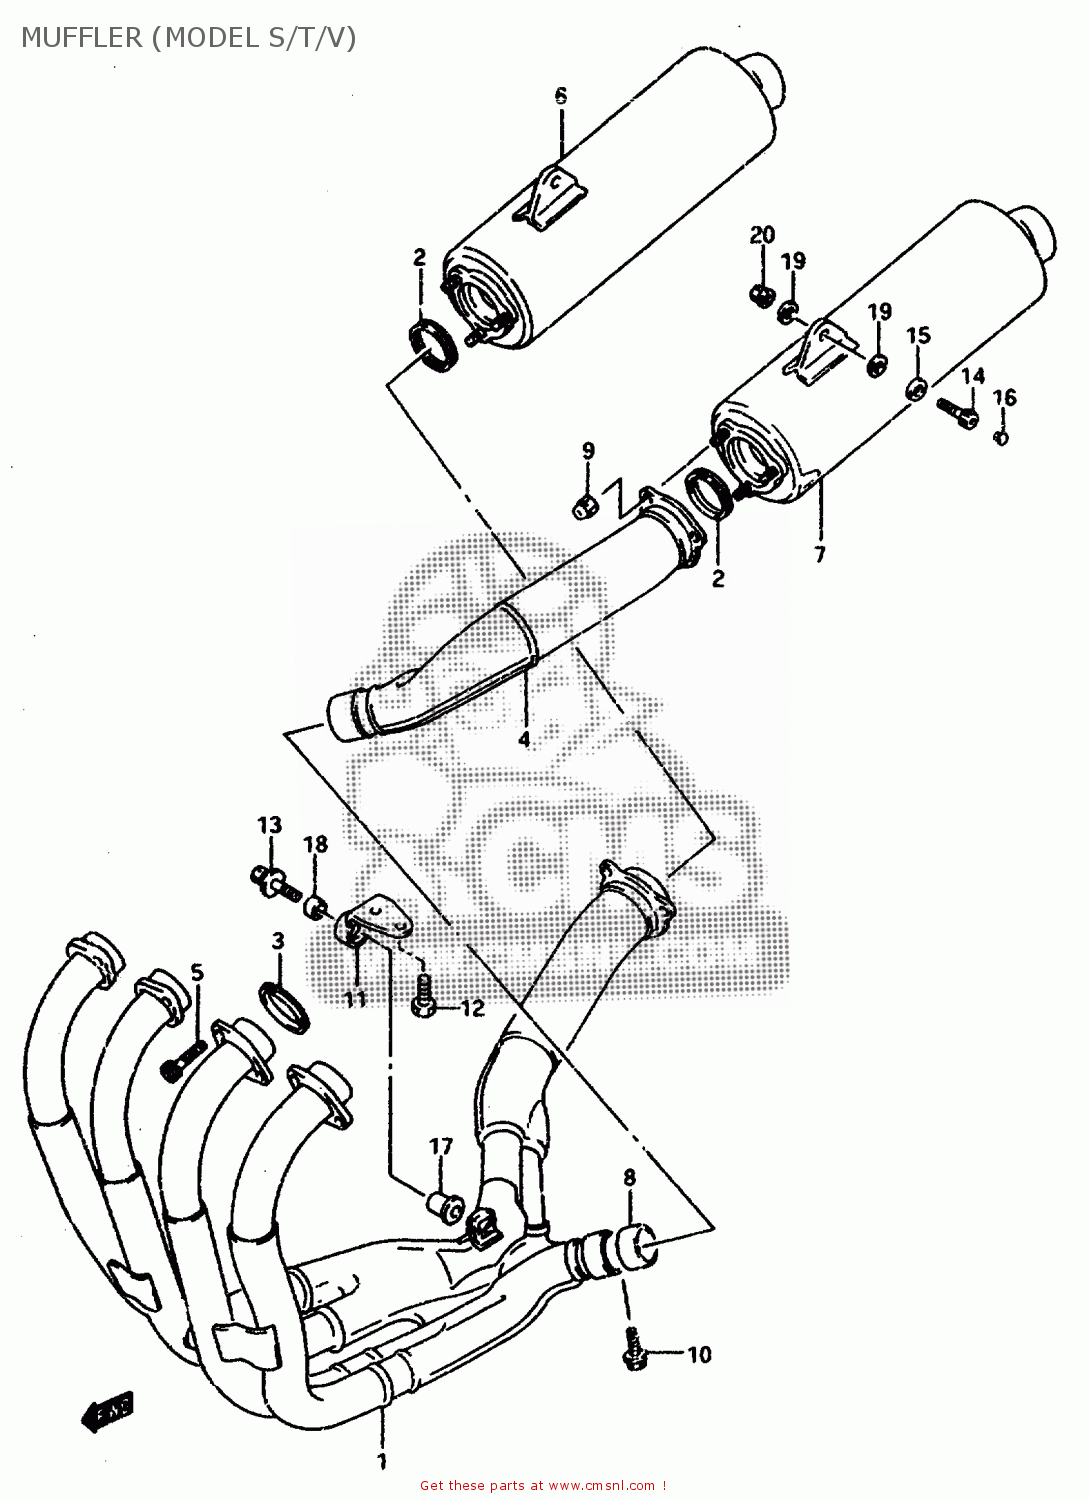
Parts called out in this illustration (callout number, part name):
1	EXHAUST
2	GASKET,MUFFLER JOINT
3	GASKET,EXHAUST PIPE
4	PIPE,JOINT,L
5	BOLT
6	BODY,MUFFLER.R
7	BODY,MUFFLER,L
8	CONNECTOR,MUFFLER
9	NUT
10	BOLT
11	BOLT(8X20)
12	BOLT(8X20)
13	BOLT
14	BOLT
15	WASHER
16	WASHER (10.5X24X2.3)
17	NUT
18	CUSHION
19	WASHER (10.5X24X2.3)
20	NUT
